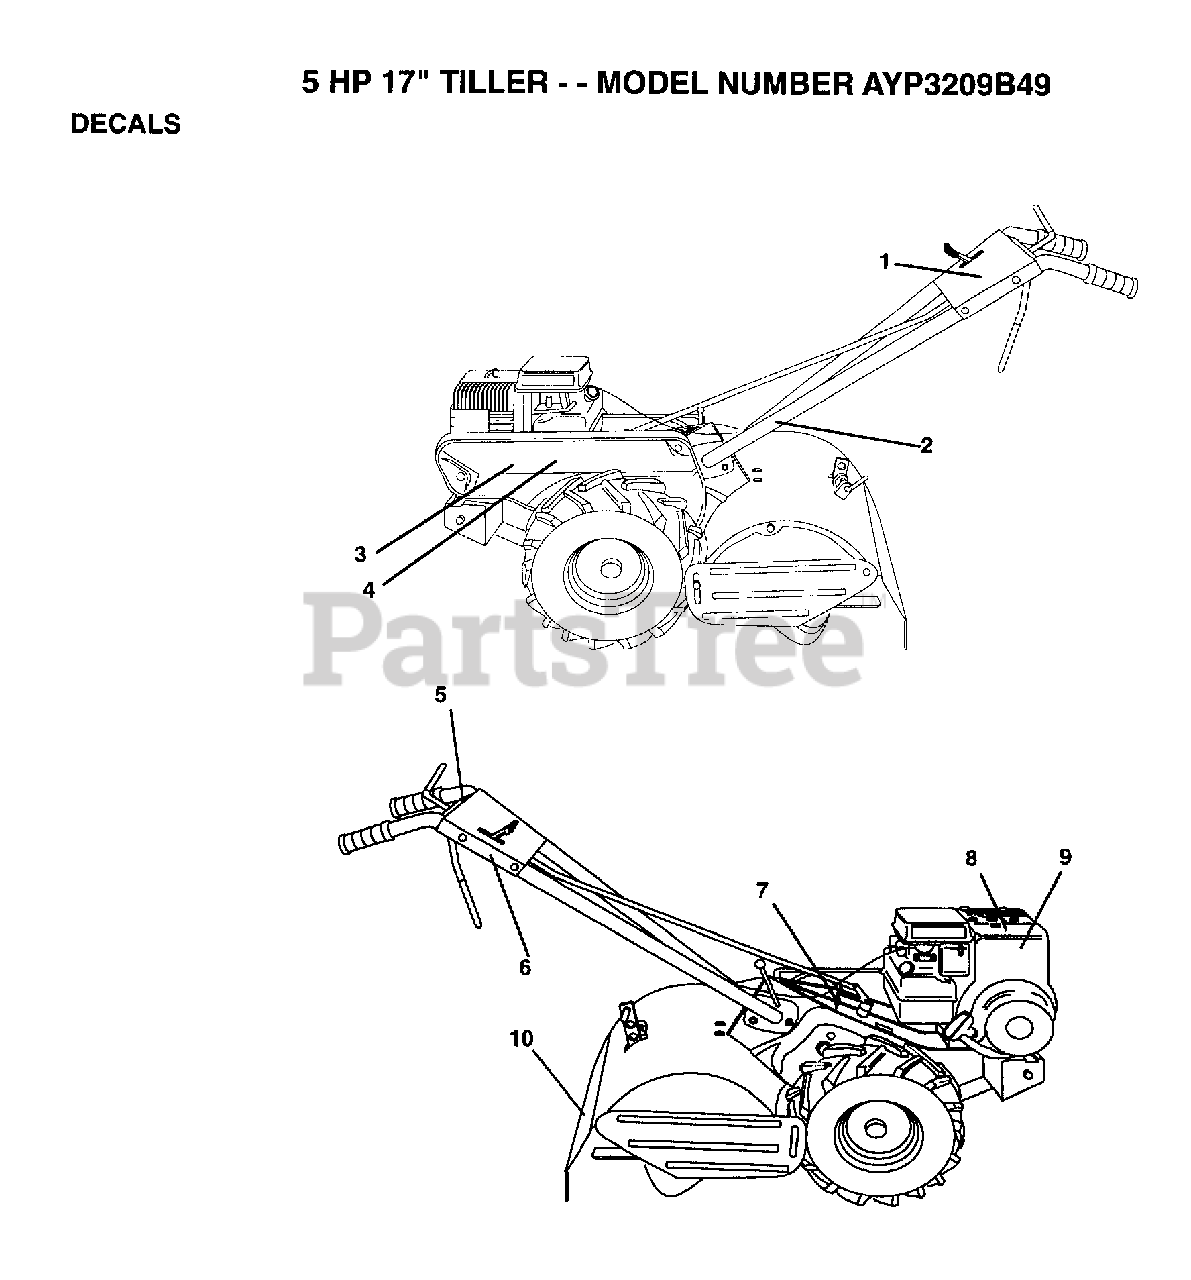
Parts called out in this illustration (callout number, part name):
1	DECAL LOGO WIZARD
6	DECAL TI
7	DECAL CRT
10	DECAL TI
